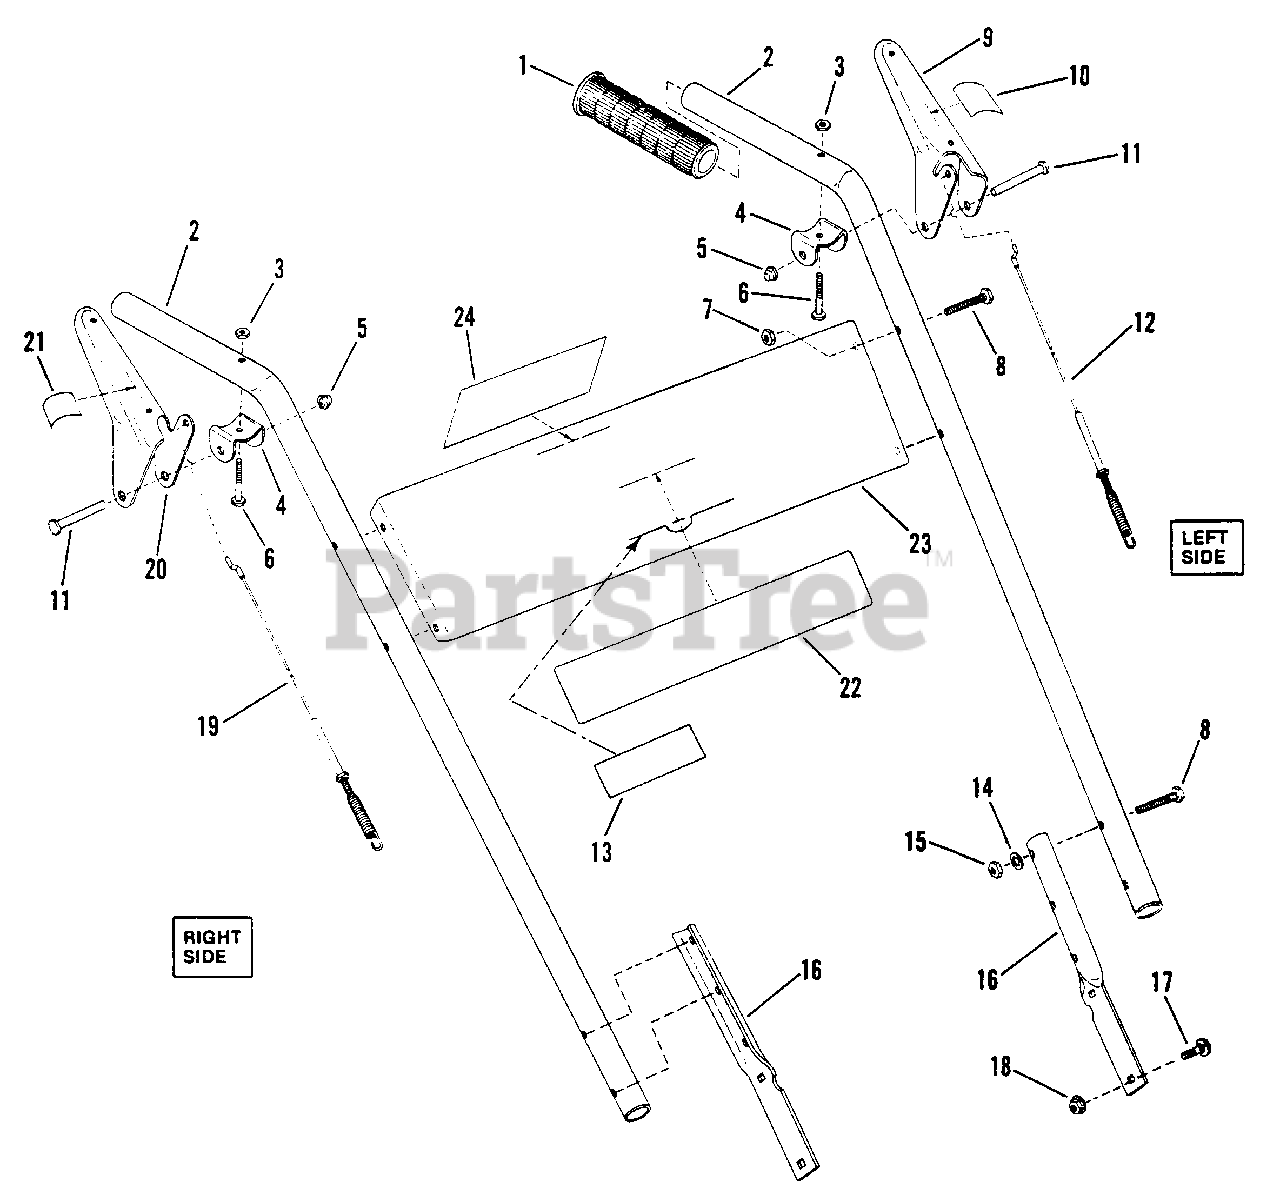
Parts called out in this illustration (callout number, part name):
1	GRIP, Handle
2	BAR, Handle (SERIES 0)
3	NUT, 1/4-28 Hex Top Lock
4	BRACKET, Handle
5	NUT, 1/4 Push
6	SCREW, 1/4-28 x 1-3/8" Hex Head Cap
7	NUT, 5/16-18 Hex Center Lock
8	SCREW, 5/16-18 x 1-1/2" Hex Head Cap
9	HANDLE, Left Side
10	DECAL, Traction Clutch (SERIES 0)
11	PIN, 1/4x1-7/8" Clevis
12	CABLE, Clutch Left Side (Short)
13	DECAL, Model 4220
14	WASHER, 5/16 Internal Tooth Lock
15	NUT, 5/16-18 Hex
16	BRACE, Handle Bar
17	BOLT, 5/16-18 x 5/8" Carriage
18	NUT, 5/16-18 Hex Flange Lock
19	CABLE, Auger Right Side (Long)
20	HANDLE, Right Side
21	DECAL, Blower Clutch (SERIES 0)
22	DECAL, SNAPPER (SERIES 0)
23	PANEL, Control
24	DECAL, Instruction
